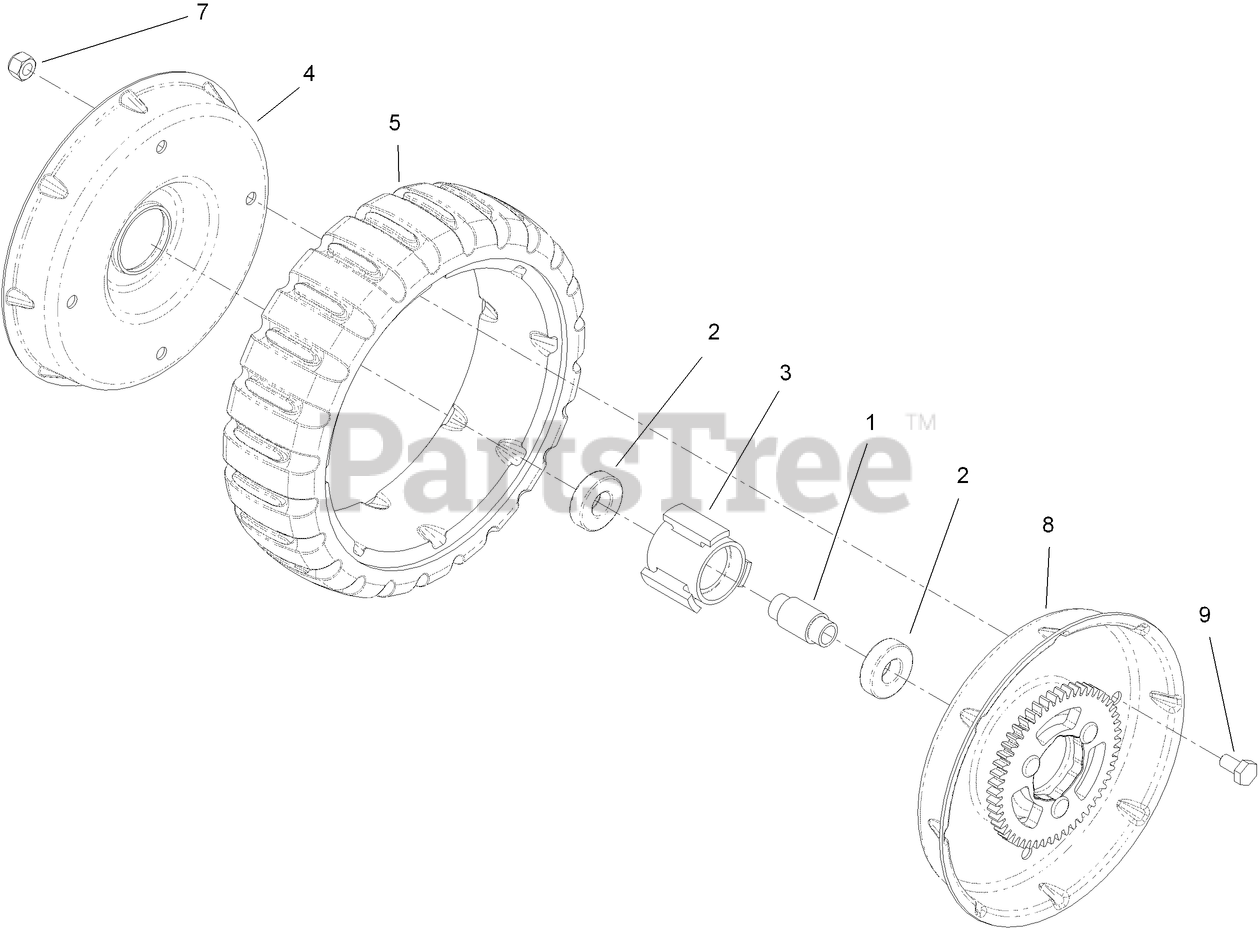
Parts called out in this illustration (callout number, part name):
1	SPACER-BEARING
2	BEARING-WHEEL
3	HUB-BEARING
4	WHEEL-HALF
5	TIRE-8 INCH
7	NUT-LOCK, NI
8	HUB GEAR ASM
9	SCREW-HH
